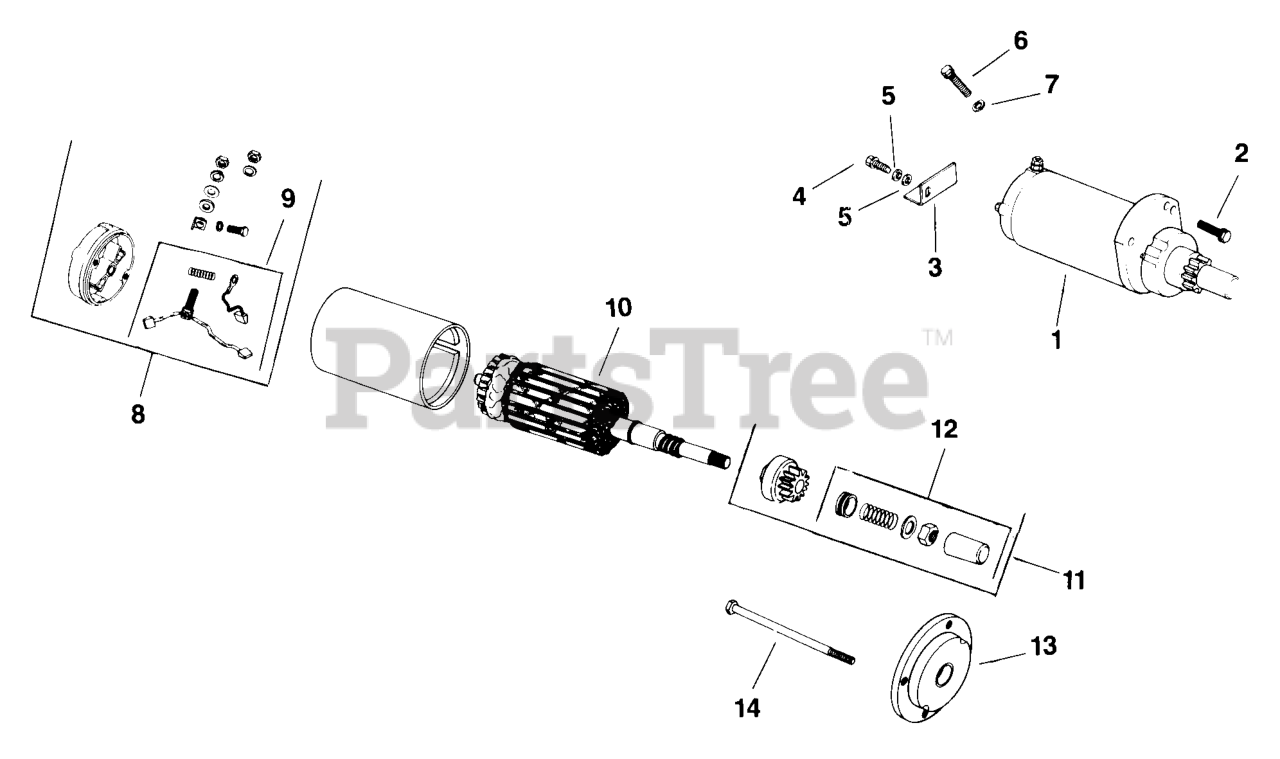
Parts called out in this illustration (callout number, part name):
1	STARTER - USE 48 098 04
8	CAP - DISCONTINUED
9	KIT - USE 52 755 15
10	ARMATURE - DISCONTINUED
11	DRIVE KIT - USE 48 755 40
12	DRIVE KIT - USE 48 755 40
13	CAP - DISCONTINUED
14	BOLT - (#DSC)
